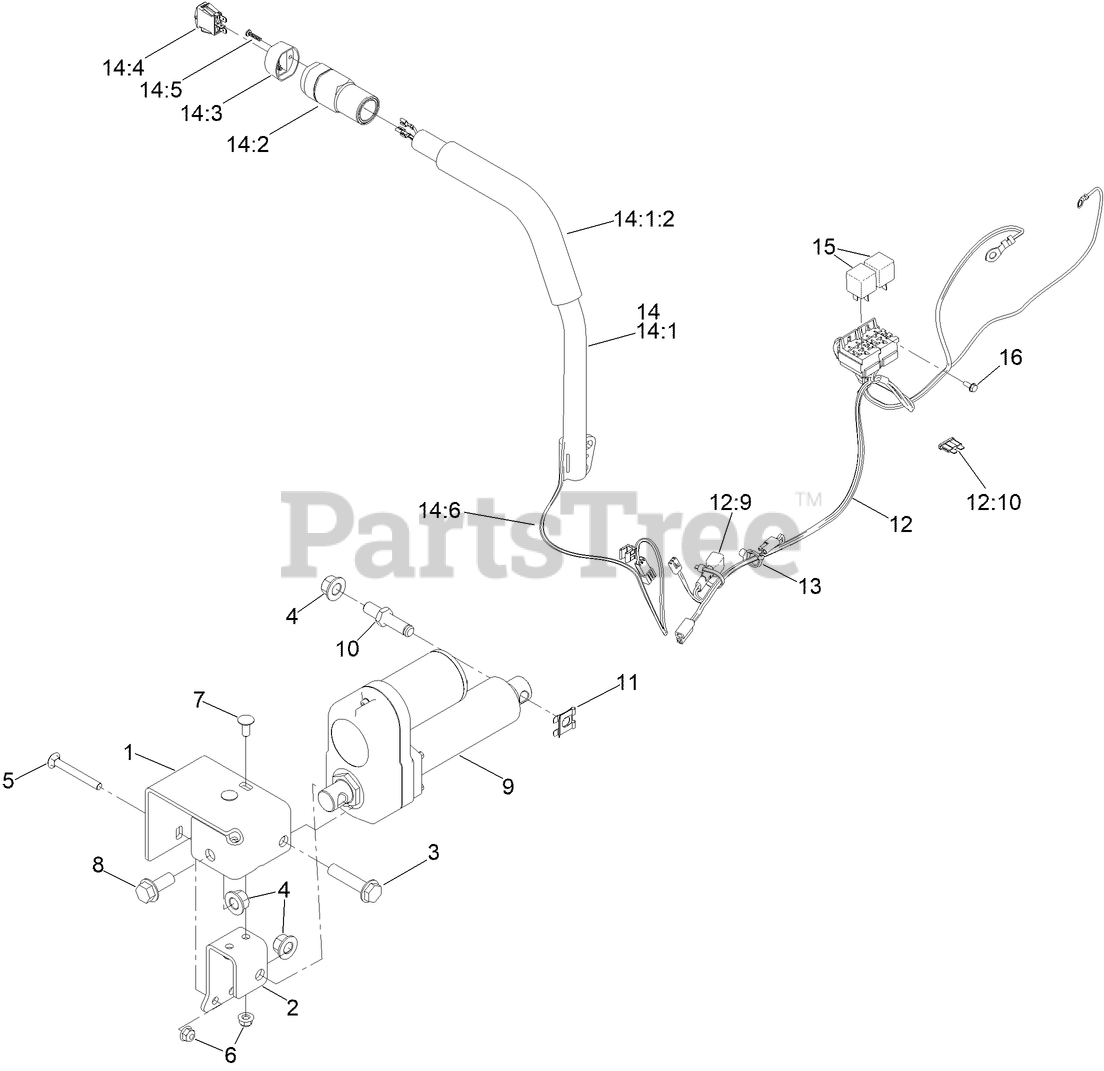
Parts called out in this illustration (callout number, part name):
1	BRACKET-MOUNT, OUTER
2	BRACKET-MOUNT, INNER
3	SCREW-HHF
4	NUT-LOCK
5	SCREW-CARR
6	NUT-HF, NI
7	BOLT-CARR
8	SCREW-HHF
9	ACTUATOR-LINEAR
10	PIN-PIVOT, ACTUATOR
11	CLIP-PIN
12	HARNESS-WIRE, DECK LIFT
12:10	FUSE-BLADE, 20 AMP
13	CLIP-TIE
14	HANDLE ASM-LH
14:1	HANDLE ASM - LH
14:1:2	GRIP-CONTROL, LEVER
14:2	CASE ASM
14:3	CAP-SWITCH
14:4	Air Cleaner Element
14:5	SCREW-PPH
14:6	HARNESS-WIRE, HANDLE
16	SCREW-TAPTITE
